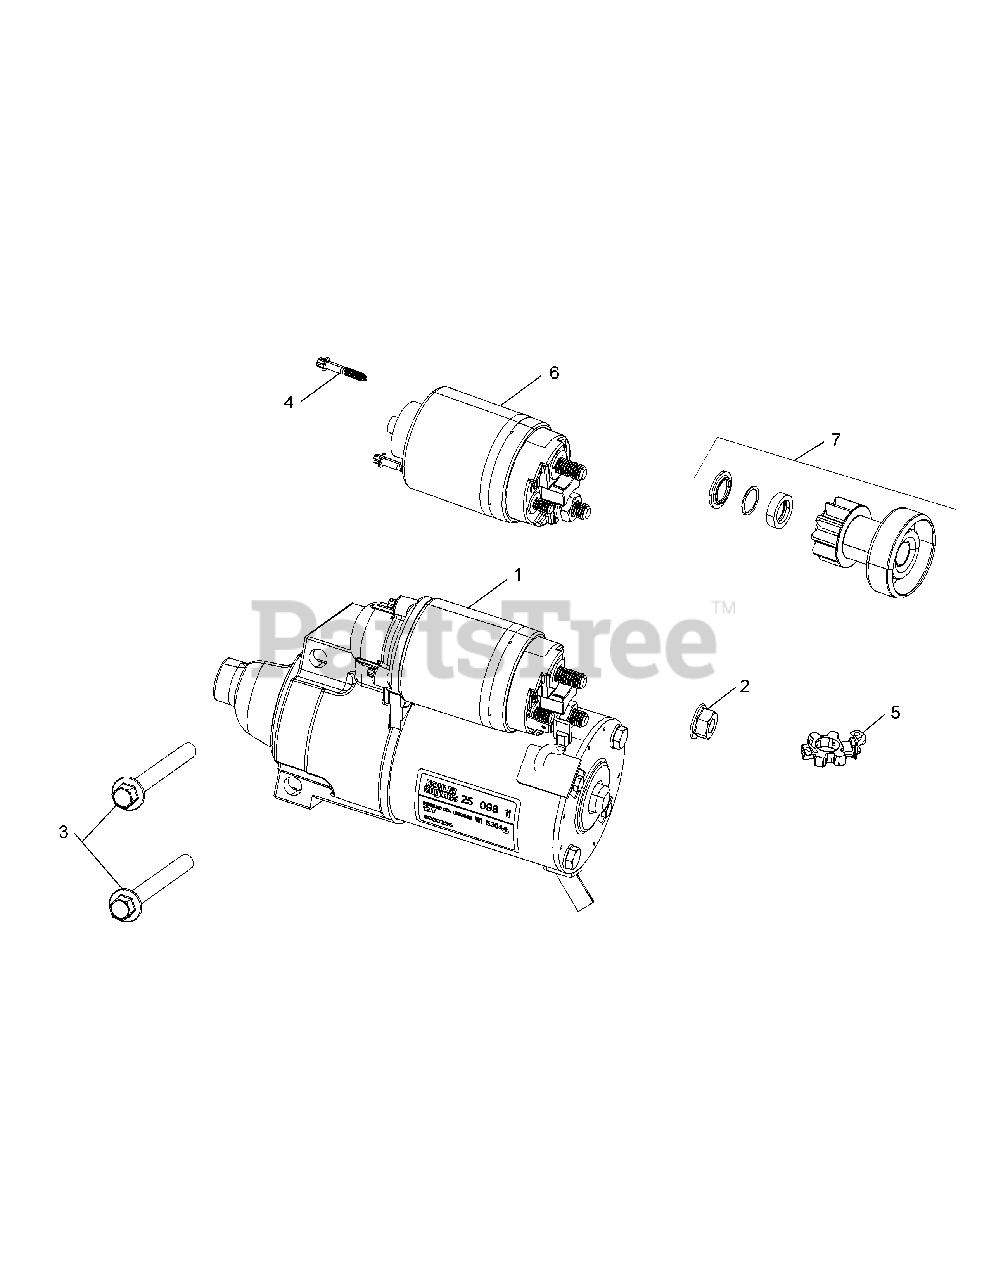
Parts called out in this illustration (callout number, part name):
1	Solenoid Shift Starter Assembly
2	Flange Nut, M8x1.25
3	Flange Screw, M8 x 1.25 x 80
4	Torx Head Screw
5	Brush Holder Kit
6	Solenoid Kit (Inc. 4)
7	Starter Pinion Kit
